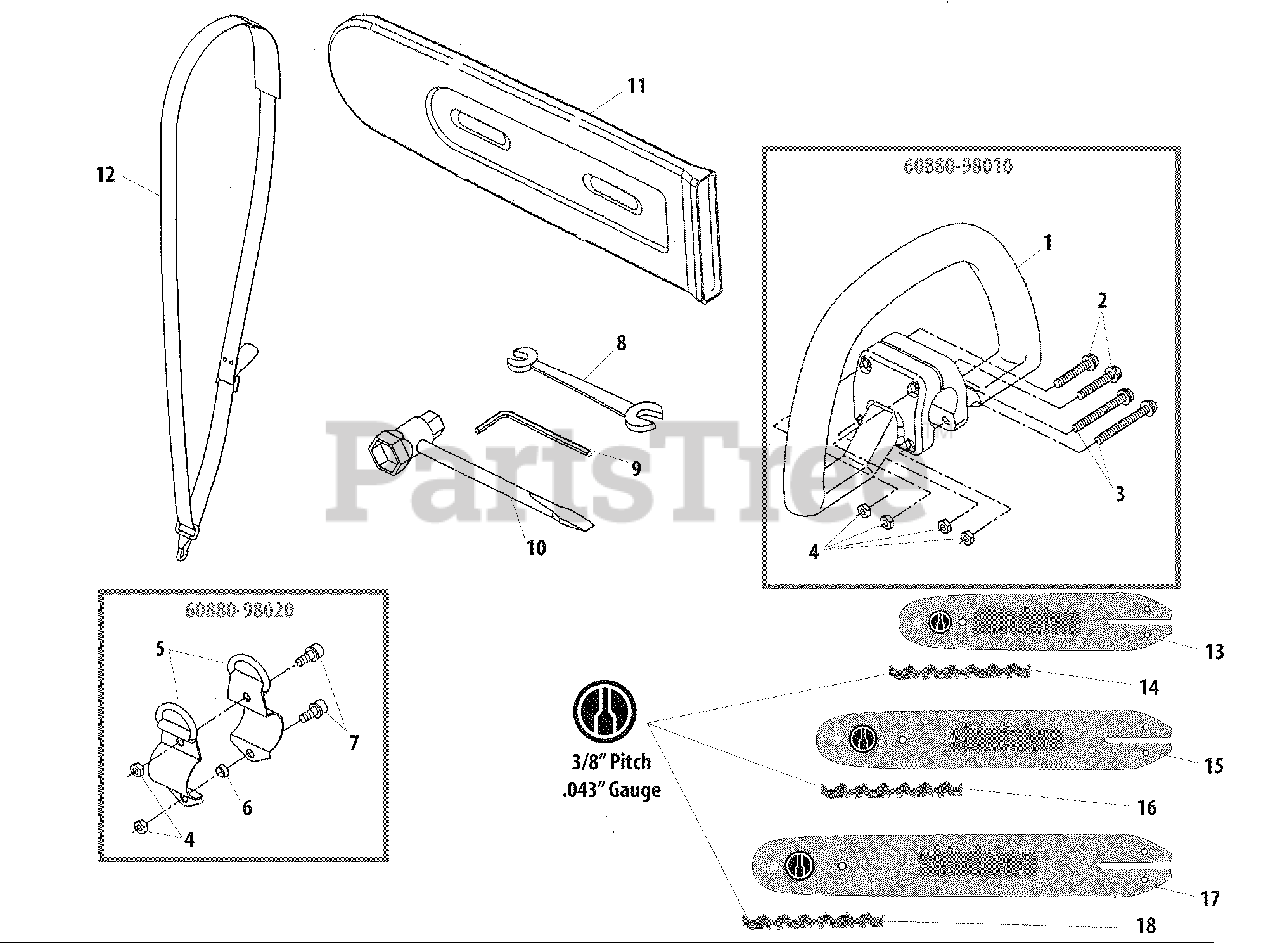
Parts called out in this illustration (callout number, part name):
2	SCREW M5×30
3	SCREW - 5×45
4	NUT M5
5	HANGER SET
7	BOLT M5×12
8	SPANNER 8×10
9	WRENCH, ALLEN 4 MM
10	T-WRENCH
11	SCABBARD
12	STRAP ASSY
13	GUIDE BAR - 8"
14	SAW CHAIN 8"
15	GUIDE BAR - 10"
16	SAW CHAIN 10"
18	SAW CHAIN 12"
60880-98010	HANDLE ASSY
60880-98020	HANGER ASSY
